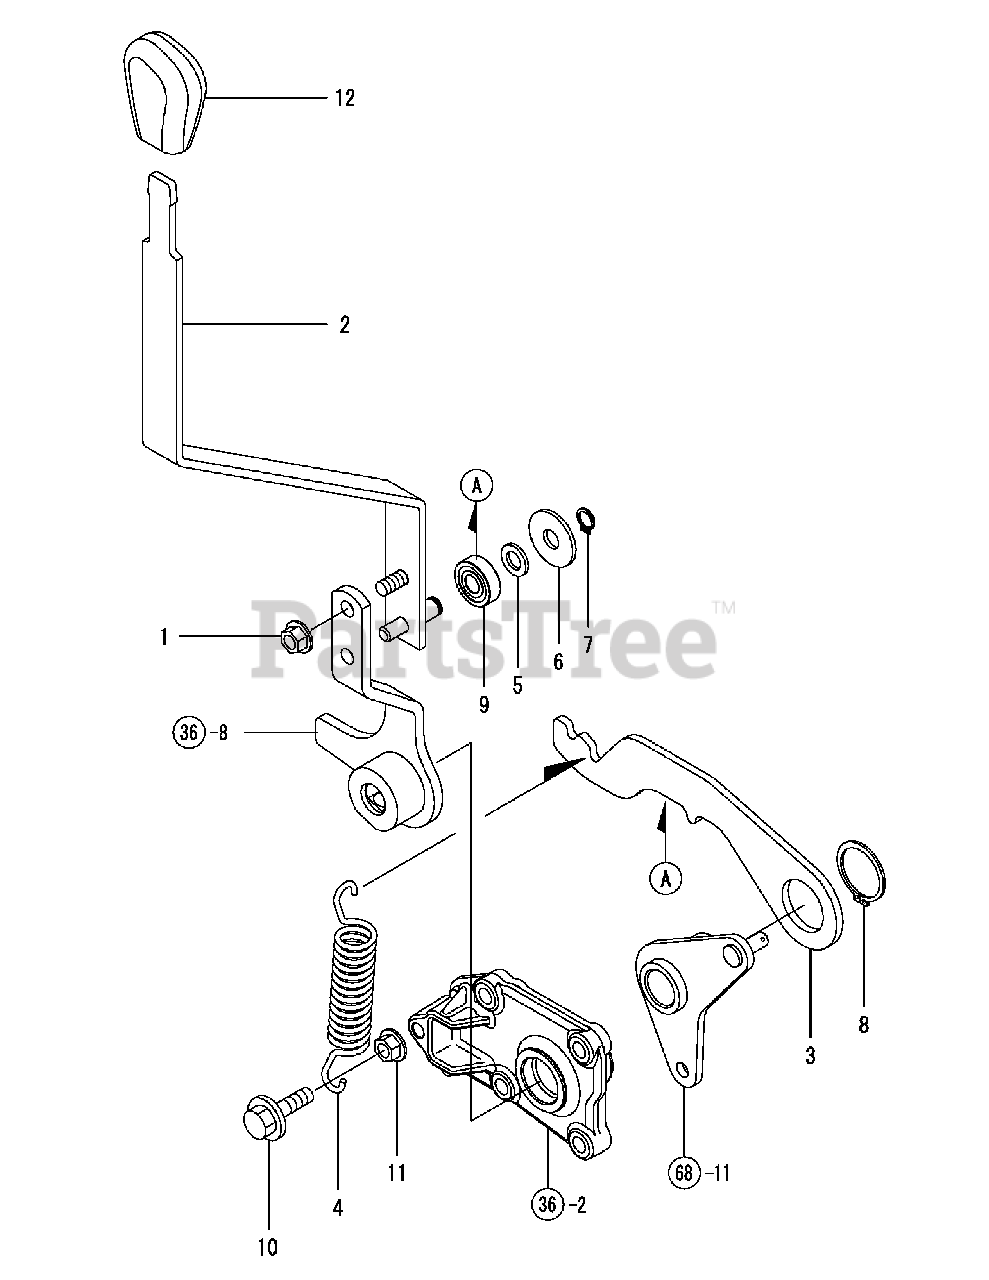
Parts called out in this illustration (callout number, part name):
1	NUT W/WASHER 8
2	LEVER CMP, RANGE
10	BOLT M 8X 25 PLATED
12	KNOB, ORANGE
